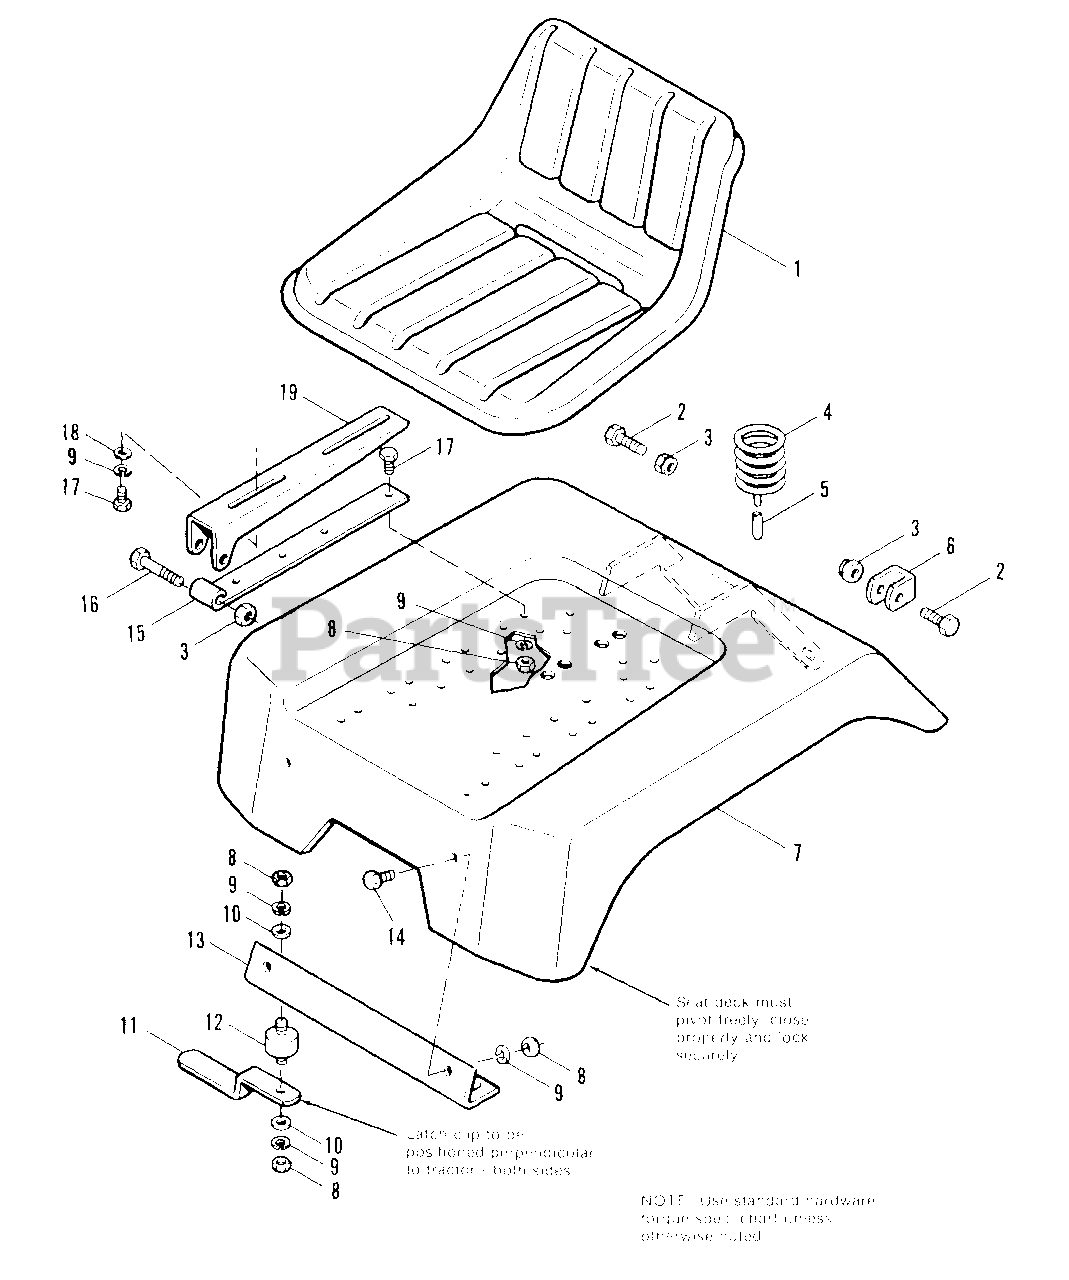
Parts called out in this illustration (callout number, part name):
1	SEAT ASSY., Contour
2	CAPSCREW, Hex Hd., 3/8-16 x 1-1/4
3	LOCKNUT, Hex, 3/8-16
4	SPRING, Seat
5	COVER, Wire
6	STOP, Seat Deck
7	DECK ASSY., Seat
8	NUT, Hex, Full, 5/16-18
9	LOCKWASHER, 5/16
10	WASHER, Plain, 1/4
12	CONNECTOR, Cushion
13	BRACKET, Seat Deck, Front
14	CAPSCREW, Hex Hd., 5/16-18 x 5/8
15	HINGE, Lower
16	CAPSCREW, Hex Hd., 3/8-16 x 2
17	CAPSCREW, Hex Hd., 5/16-18 x 3/4
18	WASHER, Plain, 5/16
19	HINGE, Upper
